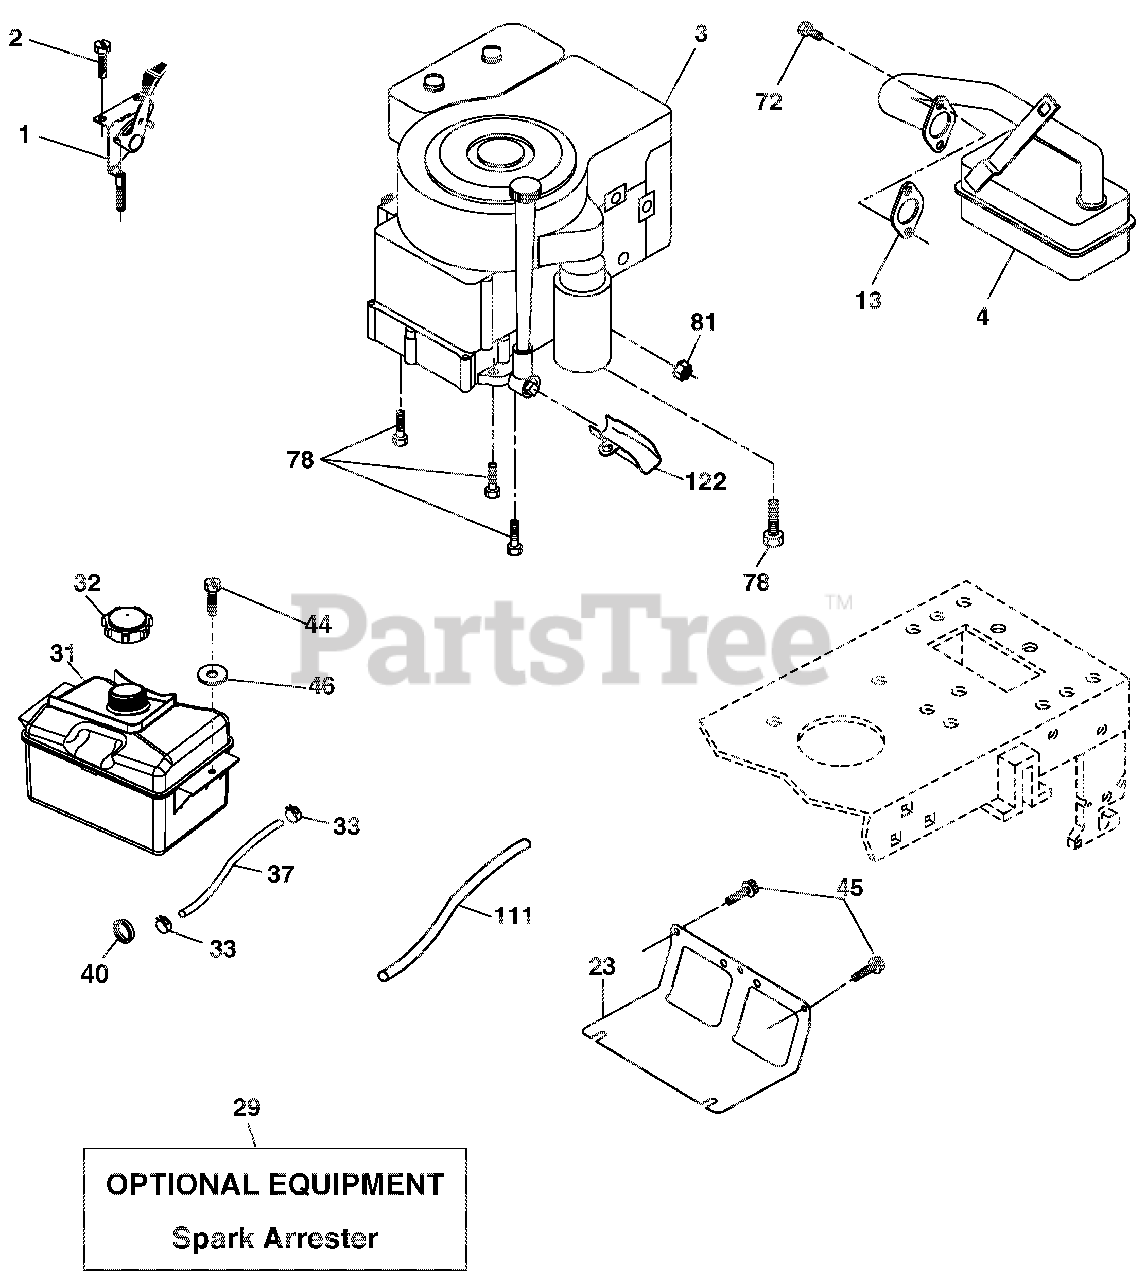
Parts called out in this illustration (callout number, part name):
1	Control Th/ch Flag
2	Screw 1/4-20 x 1/2
3	ENGINE, B&S 31C707-3346-G5(438207) (ORDER PARTS FROM ENGINE MANUFACTURER.)
4	Muffler Exhaust B&S
13	Gasket Eng 1 313 Id Tin Plated
23	Shield BRN/DBR Guard
29	KIT.SPARK ARRESTOR(392390 B&S)
31	TANK FUEL
32	CAP.FUEL
33	CLAMP.HOSE.BLK.
37	LINE.FUEL.22"FRONT.EMIS.CA.LP
40	Bushing Snap Nyl Blk Fuel Line
44	SCREW.HEXWSH.THDROL.1/4-20X3/4
45	SCREW.HEXWSH THDR3/8-16X3/4.BL
46	WASHER.9/32 X 7/8 X 16GA.
72	SCREW.SOCKET HD.5/16-18 X .75
78	Screw 3/8-16 x <
81	Nut, Keps Hex 1/4-20 unc
111	PURGE.LINE.CARB
122	Extension Drain Oil
